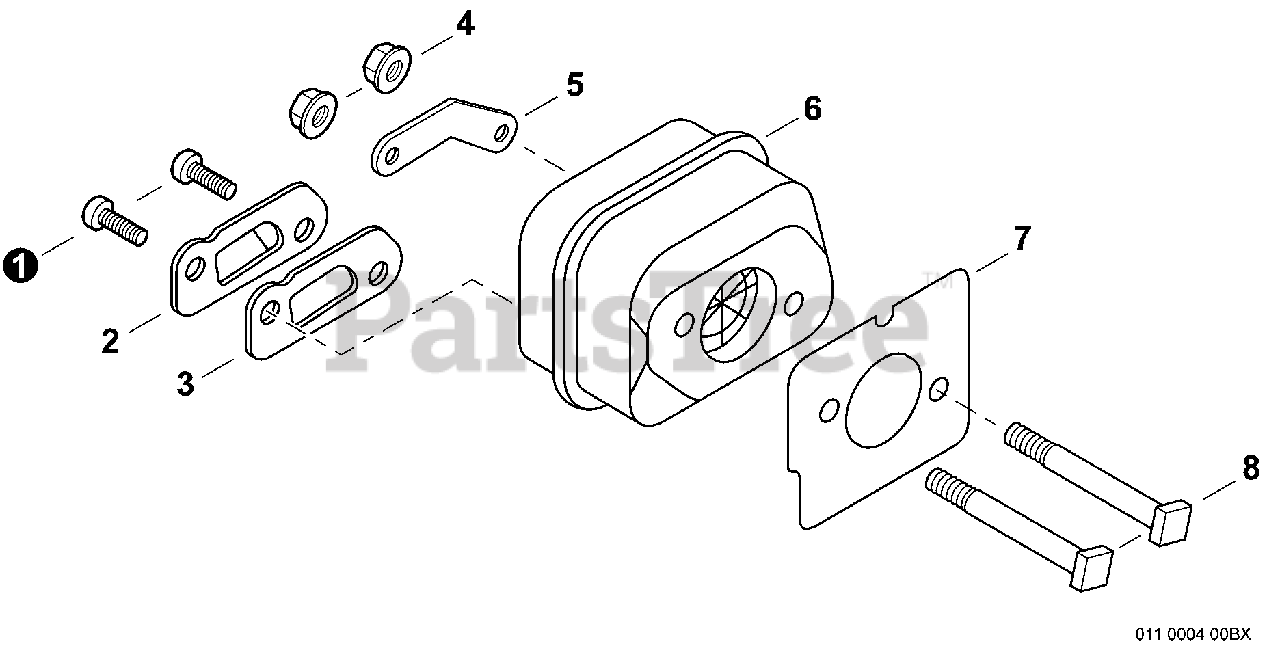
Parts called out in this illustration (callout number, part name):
1	SCREW 4×8
2	GUIDE, EXHAUST
3	SCREEN, SPARK ARRESTER
4	NUT, FLANGE M5
5	PLATE, EYE
6	MUFFLER
7	GASKET, EXHAUST
8	BOLT 5×62
